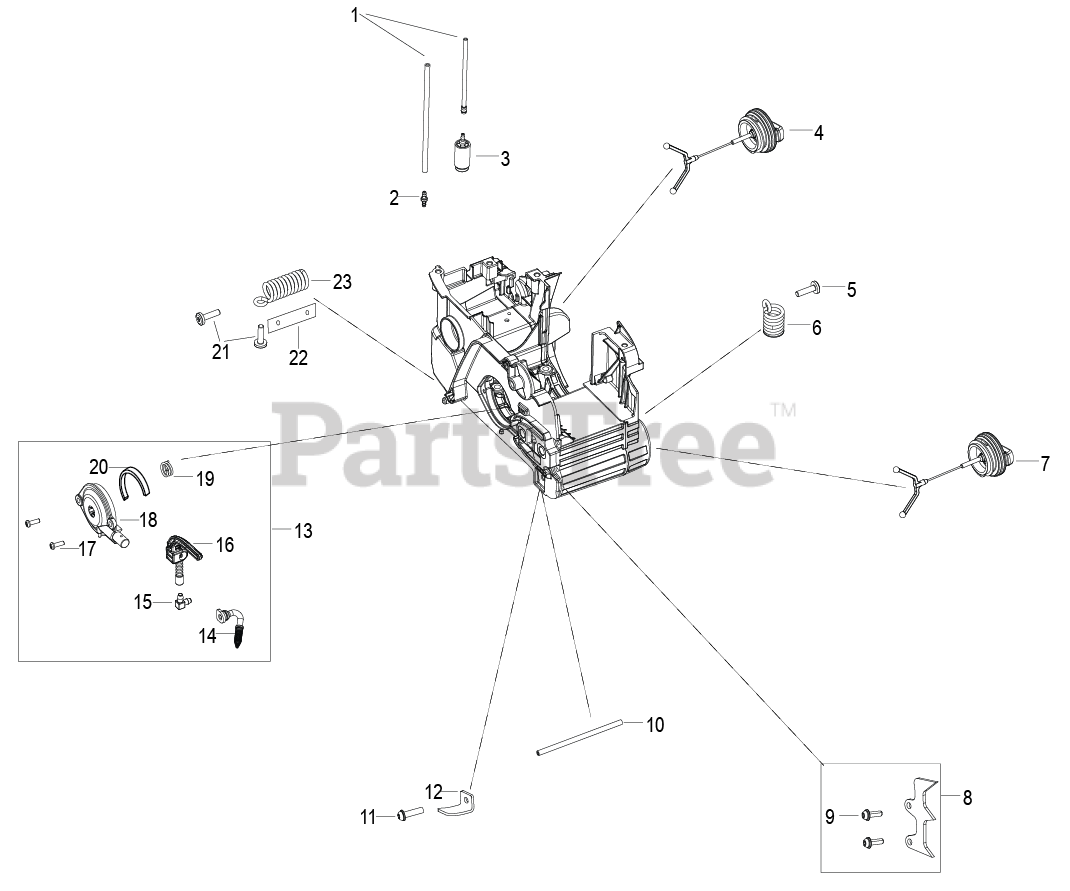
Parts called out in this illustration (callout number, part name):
1	KIT FUEL HOSE LP1200
2	Fitting - Fuel line
3	ASSY FUEL PICKUP PRE FLUSHED
4	TANK CAP ASSY
5	SCREW
7	TANK CAP ASSY
8	Kit-Spike Assy.
9	Screw
10	OIL TUBE
11	SCREW M5.38-14X22.225MM
12	CHAIN CATCHER 36/41
13	OIL PUMP KIT
14	OIL PICK UP W/FILTER ASSY
15	Elbow-Oil Pickup
16	OIL BLOCK
17	SCREW 6-19X.437
18	OIL PUMP ASSY
19	Gear-Worm Spring
20	SEAL
21	SCREW
22	STRAP
23	SPRING
